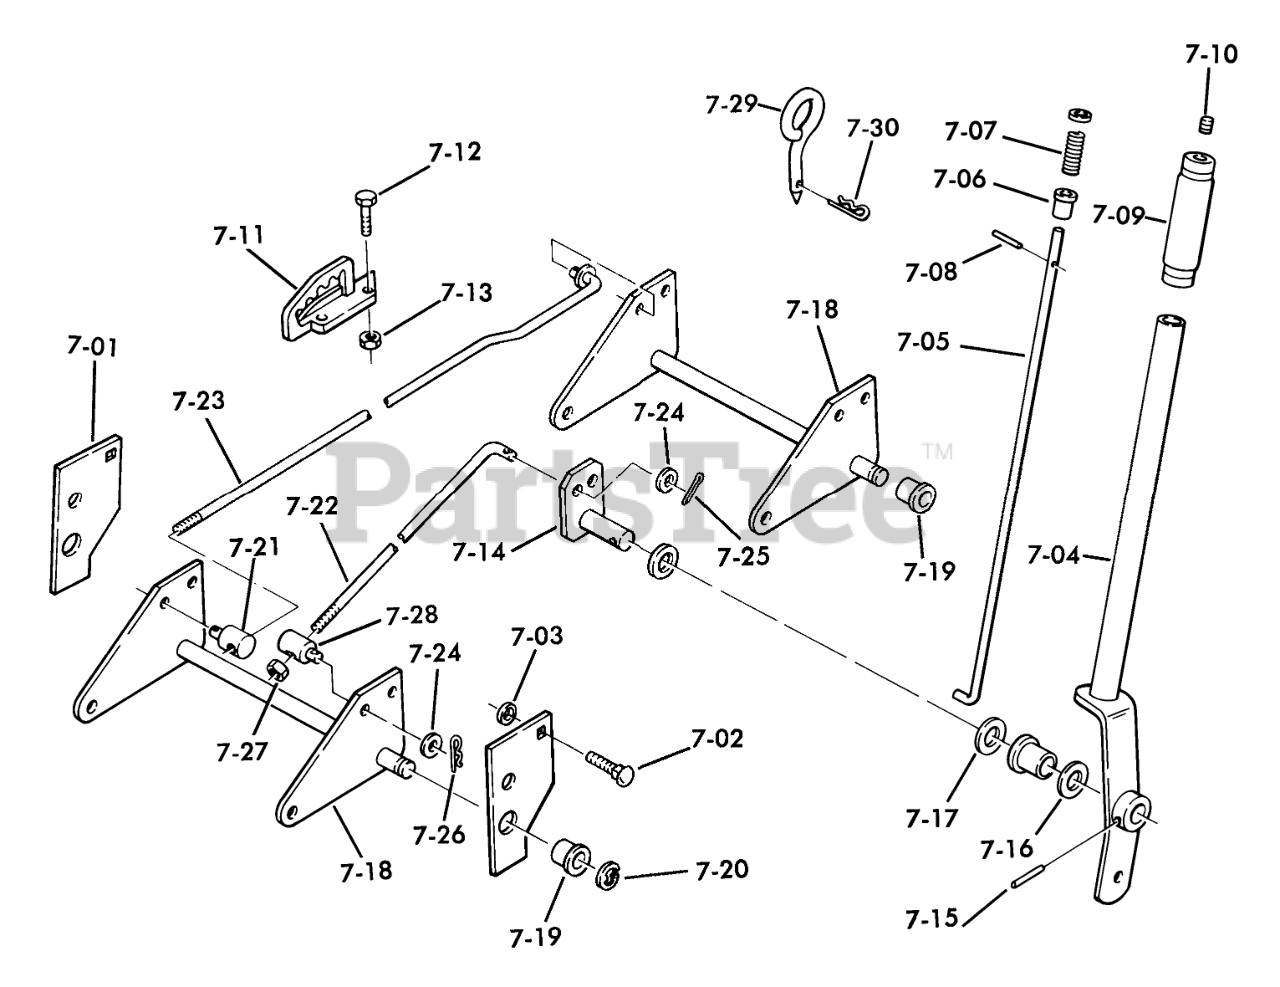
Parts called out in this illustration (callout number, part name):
7-01	Front Hitch Plate
7-02	Bolt-Carriage
7-03	Washer
7-04	Lift Lever
7-05	ROD-LATCH LIFT LEVER
7-06	RETAINER-SPRING
7-07	SPRING-COMPRESSION
7-08	PIN-SPIROL
7-09	HANDGRIP
7-10	CAP-ROD, PLUNGER
7-11	Height Control Quadrant
7-12	BOLT
7-13	Nut
7-14	Assy-Lift Arm
7-15	PIN-ROLL, SPIROL
7-16	WASHER
7-17	Washer
7-18	Assy-Lift Bell Crank
7-19	BRONZE BUSHING
7-20	E Ring
7-21	TRUNNION
7-22	LIFT ROD-FRONT
7-23	Lift Rod-Rear
7-24	Washer
7-25	Pop Rivet
7-26	Hairpin
7-27	NUT
7-28	TRUNNION-LIFT
7-29	Pin-Tool
7-30	Hairpin Cotter
